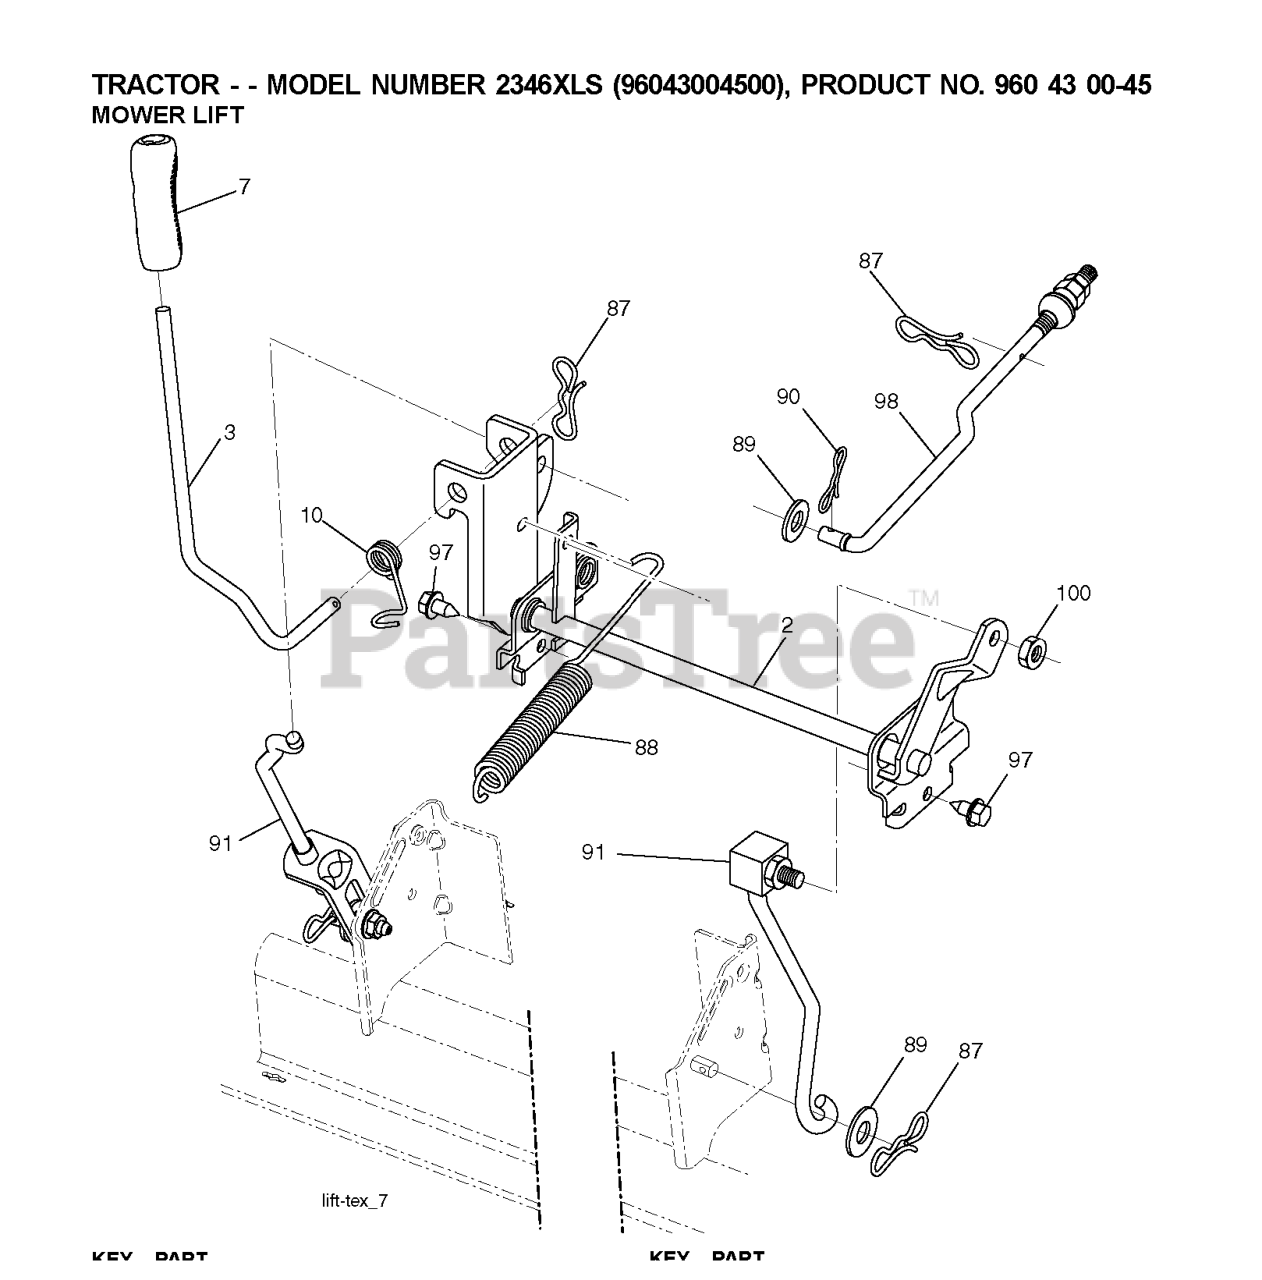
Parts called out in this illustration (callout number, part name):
2	SHAFT.ASM.LIFT.CROSS.H
3	LEVER.LIFT.HANDLE.GT
7	GRIP.HANDLE.LIFT.PVC.BLACK
10	SPRING.TORSION.LIFT.HANDLE
87	PIN.COTTER.7/16.BOW TI.
88	SPRING.LIFT.ASSIST
89	WASHER.CLEAR.ZINC
90	PIN.COTTER.5/16.BOW TI
91	LINK.ASM.LIFT.REAR
97	SCREW, 3/8-16X3/4
98	LINK.ASM.SUSP.FRONT.MW
100	LOCKNUT
